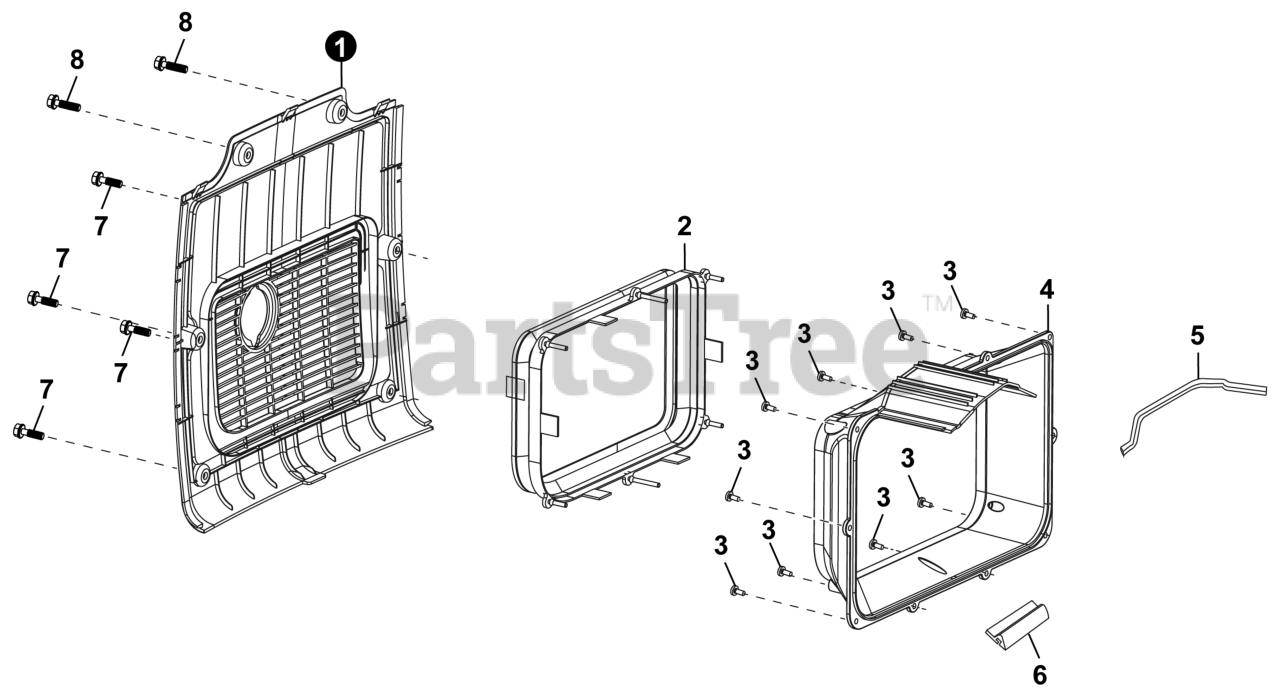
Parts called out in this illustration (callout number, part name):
1	COVER, MUFFLER SIDE
2	COVER, MUFFLER INNER
4	COVER, MUFFLER OUTER
5	STRIP, SHROUD SEAL
6	STRIP, SHROUD SEAL
